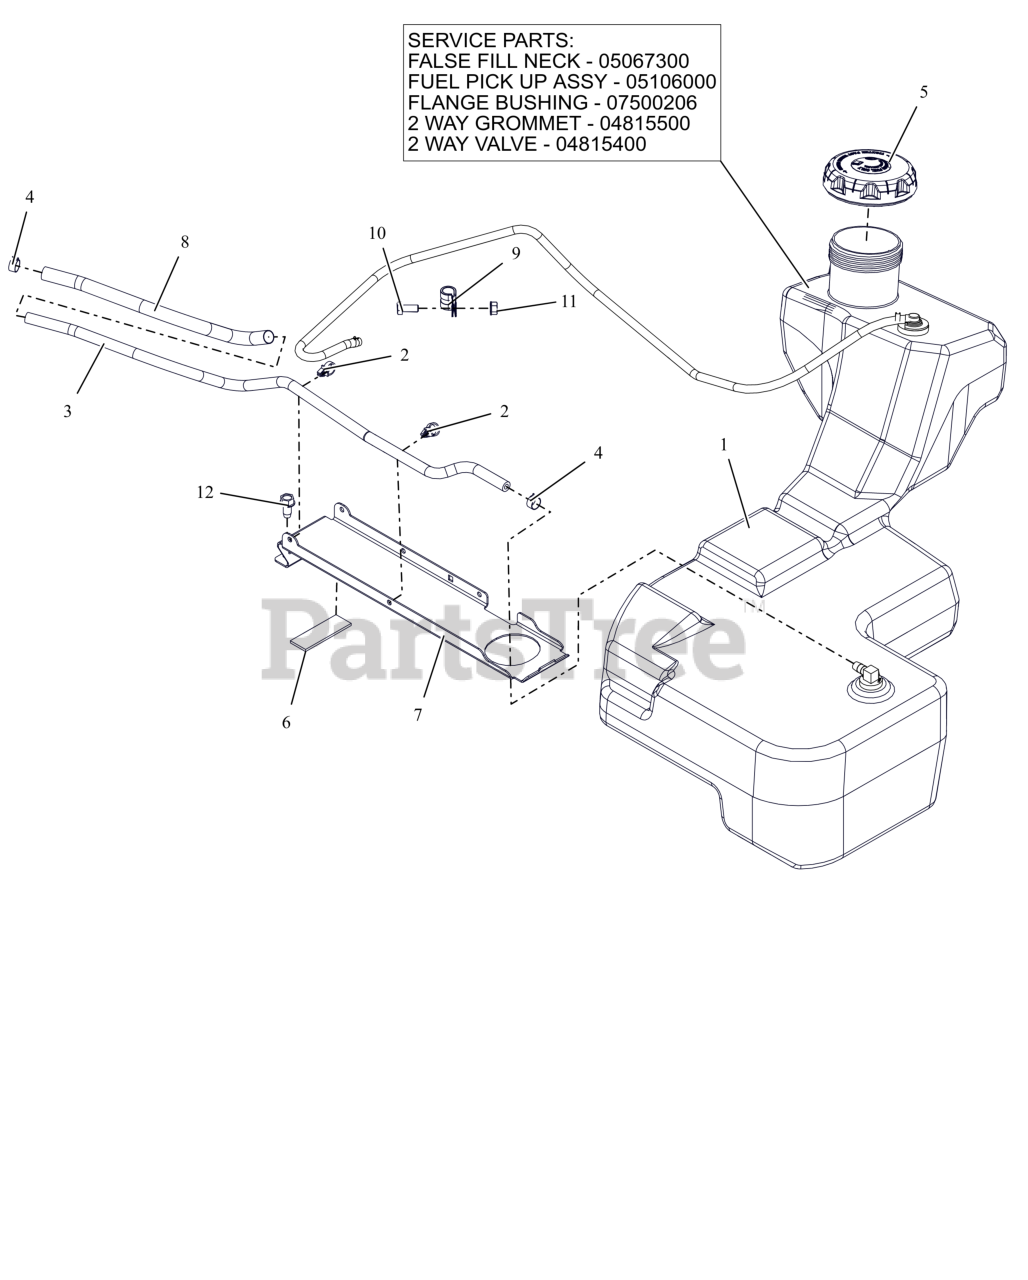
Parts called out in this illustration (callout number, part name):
1	ASM, FUEL TANK-HD
1	INSERT, FUEL NECK FALSE FILL
1	ASM, HD FUEL PICK-UP
1	BSHG-FLG .375X1.062X.625 NITR
1	GROMMET, 2-WAY
1	VALVE, 2-WAY
2	ROUTING CLIP (1/2" ID)
3	HOSE, .25 LOW-PERM BULK GAS
4	CLAMP, FUEL LINE
5	CAP, FUEL VENTIN AUTOLOCK
6	PAD,RBR 1.0"X3.0" W/ADHESIVE
7	BRKT, FUEL TANK HOLD DOWN
8	SLEEVE, THERMAL 12"
9	CLAMP, CUSHIONED STEEL
10	BLT,HEX .31-18X.75 G5 ZCC
11	NUT,LK-CTR-FLG .31-18 GF ZCC
12	SCR,TAP .375-16X.75 HWH TR ZCC
